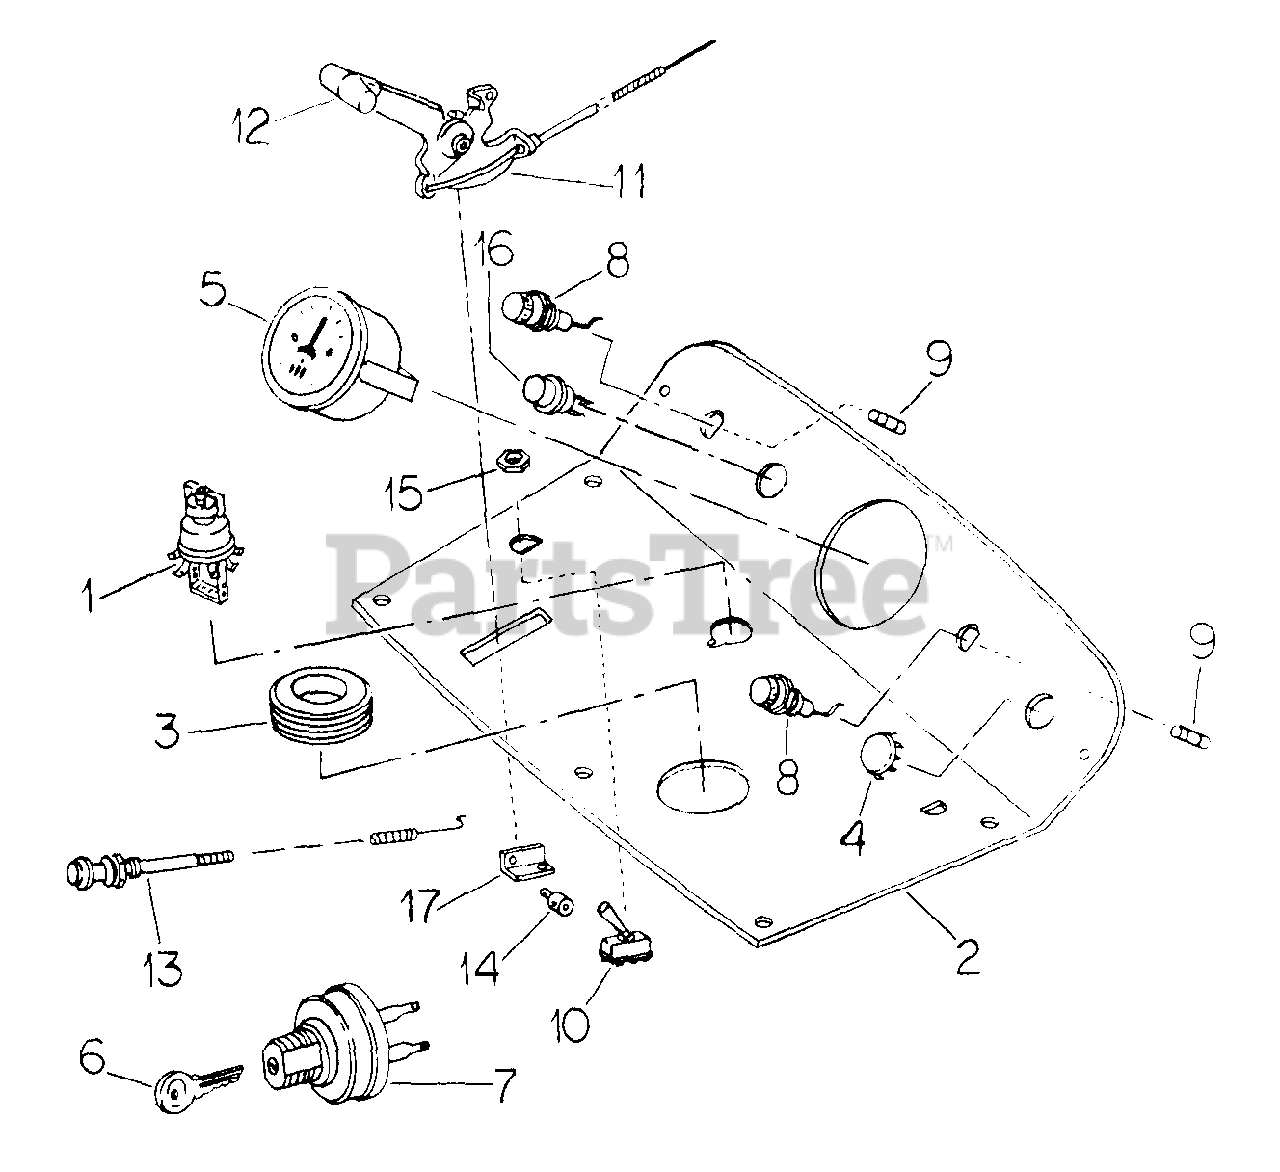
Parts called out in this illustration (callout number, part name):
1	SWITCH, LIGHTING
2	PANEL ASSY, INSTRUMENT
3	WASHER, INSTRUMENT PANEL
4	PLUG, 29/32 BUTTON CIGAR LIGHTER OPENING
5	INDICATOR, CHARGE - TRACTOR W/MOTOR-GENERATOR
6	KEY, IGNITION SWITCH
7	SWITCH, BATTERY IGNITION KEY START
8	HOUSING ASSY, FUSE
9	FUSE, CARTRIDGE TYPE AGC15
10	SWITCH, IPTO
11	LEVER, THROTTLE CABLE
12	KNOB, THROTTLE CONTROL
13	CABLE, CHOKE LEVER
14	PIN, GOVERNOR CONTROL SWIVEL
15	NUT, SWITCH
16	LIGHT ASSY, INDICATOR
17	BRACKET, THROTTLE CONTROL
